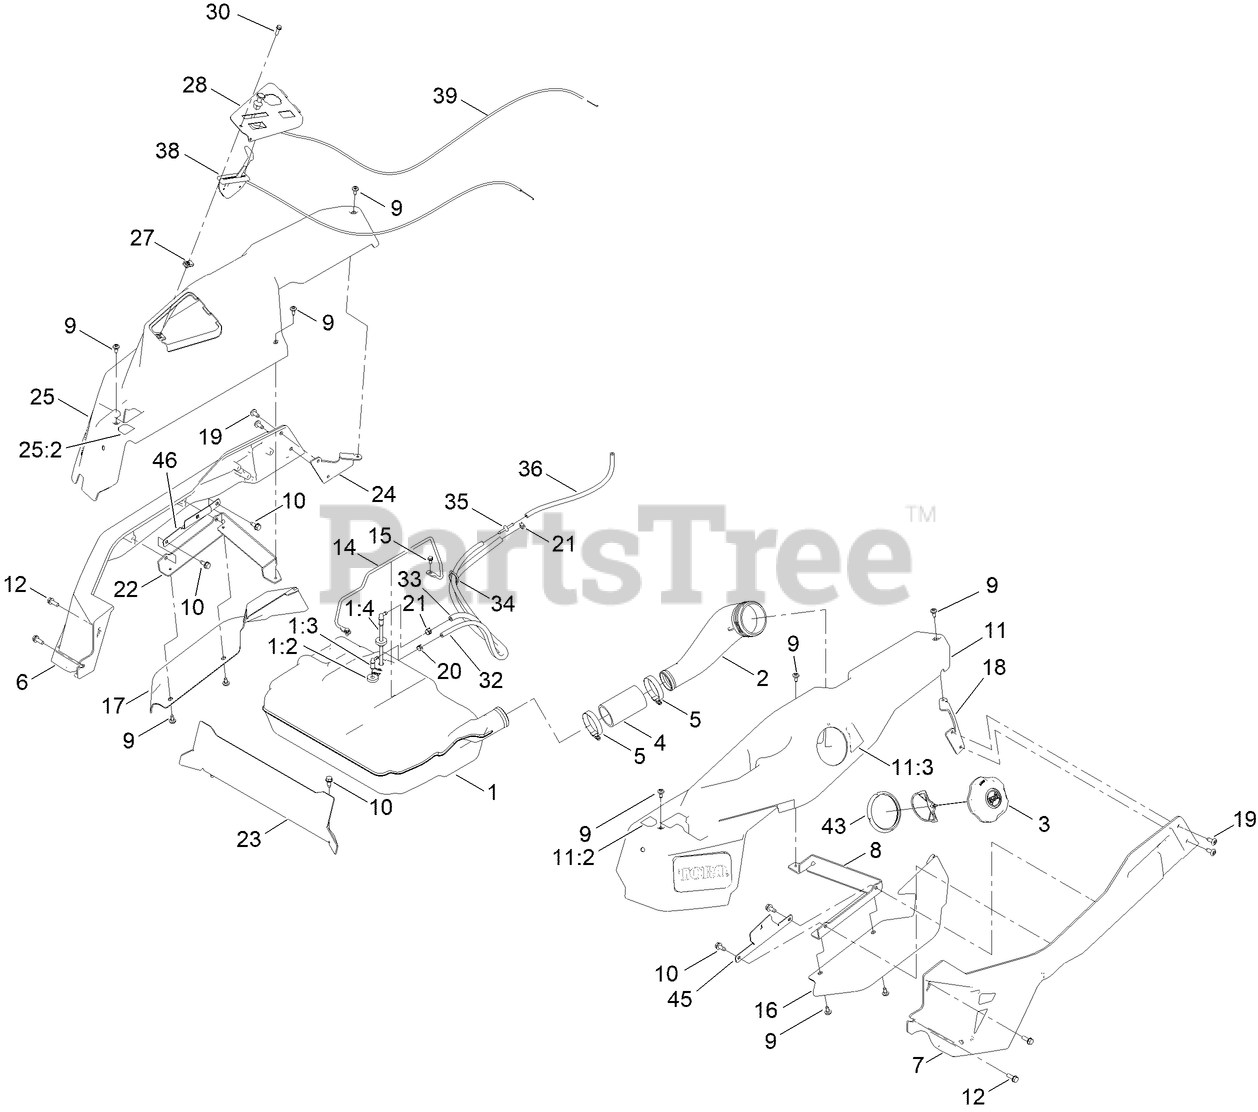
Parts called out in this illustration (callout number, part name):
1	TANK-FUEL ASM
1:2	BUSHING
1:3	FITTING-ELBOW 90
1:4	FITTING - PICKUP, FUEL
2	NECK-FILLER, FUEL
3	CAP-FUEL, RATCHETING
4	HOSE-FILLER, FUEL
5	CLAMP-HOSE
6	CAST-TUBE, RH [RED]
7	CAST-TUBE, LH [RED]
8	MOUNT-POD BRACKET LH
9	SCREW-SHOULDER
10	SCREW-HWHTF
11	POD ASM - LH W/DECALS
11:2	DECAL-CONTROL LEVER, LH
11:3	DECAL-FUEL FILL
12	SCREW-TAPTITE
14	ROD-HOLD DOWN
15	SCREW-HWH
16	FENDER-TIME CUTTER, LH
17	FENDER-TIME CUTTER, RH
18	BRACKET-REAR POD, LH
20	CLAMP-HOSE
21	CLAMP-HOSE
22	MOUNT-POD BRACKET RH
23	PLATE-KICK
24	MOUNT-POD BRACKET RH
25	POD ASM - RH W/DECALS
25:2	DECAL-CONTROL LEVER, RH
28	PANEL-CONTROL
30	SCREW-HWH
32	HOSE-FUEL
33	HOSE-FUEL
34	CLIP-TIE
35	ADAPTER ORIFICE
36	HOSE-FUEL
38	CABLE-THROTTLE
39	CABLE-CHOKE
43	RING-RETAINING
45	BRACKET-ALIGNMENT, POD LH
46	BRACKET- ALIGNMENT, POD RH
